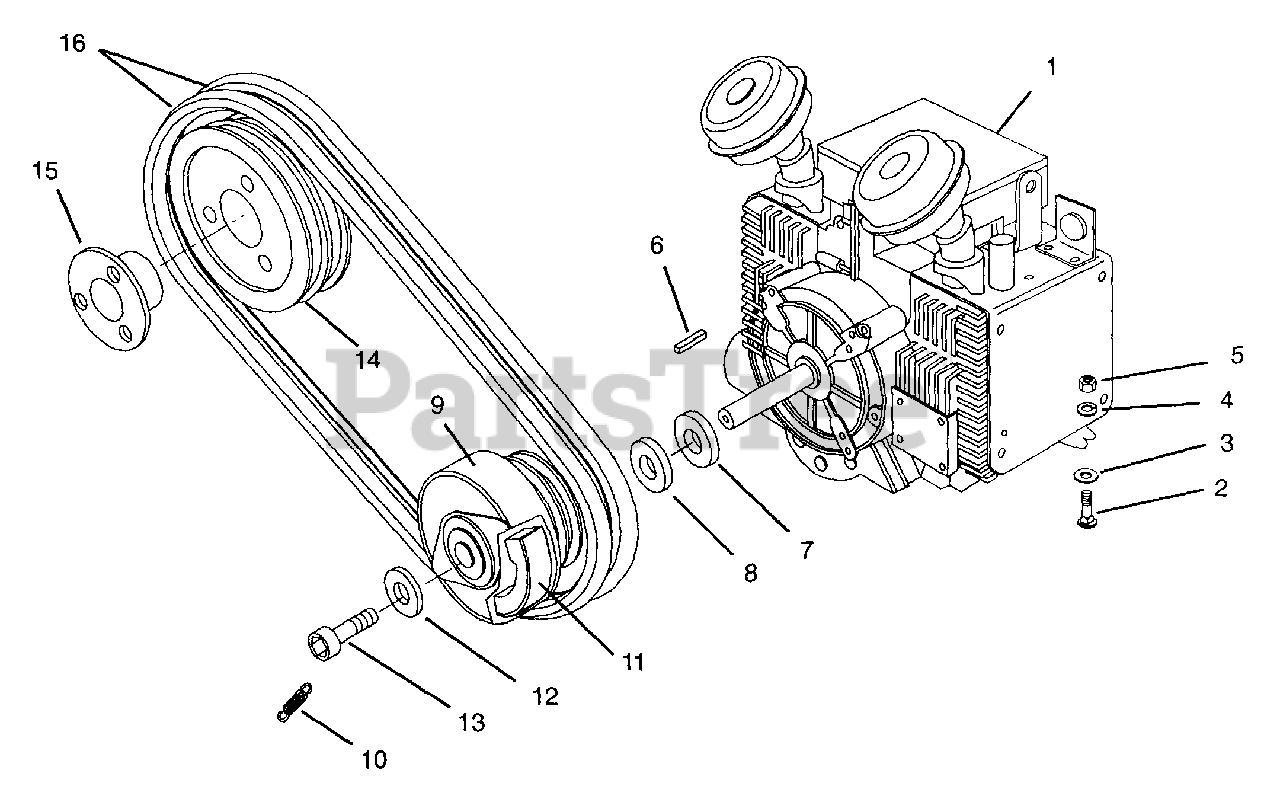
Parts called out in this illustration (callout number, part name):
1	23 H.P. Kohler Engine
2	Bolt-Round Head Square Neck .50-13 x 1.50-Grade 5
3	Washer-Flat-Steel .755 x 1.375 x .093
4	Washer-Lock .50 x .151
5	Nut .50-13
6	Key-Straight .38 x .38 x 2.75
7	Spacer-Centrifugal Clutch
8	Bushing-Narrow Rim 14 GA 1.50 x 2.25
9	Noram Clutch 1.125 Bore
10	Spring-Clutch
11	Shoe-Clutch
12	Washer-Flat .640 x 1.81 x 2.50
13	Screw-Socket Head SPL .62-18 x 1.75
15	Bushing SK x 1.50
16	V-Belt-Set of 2
